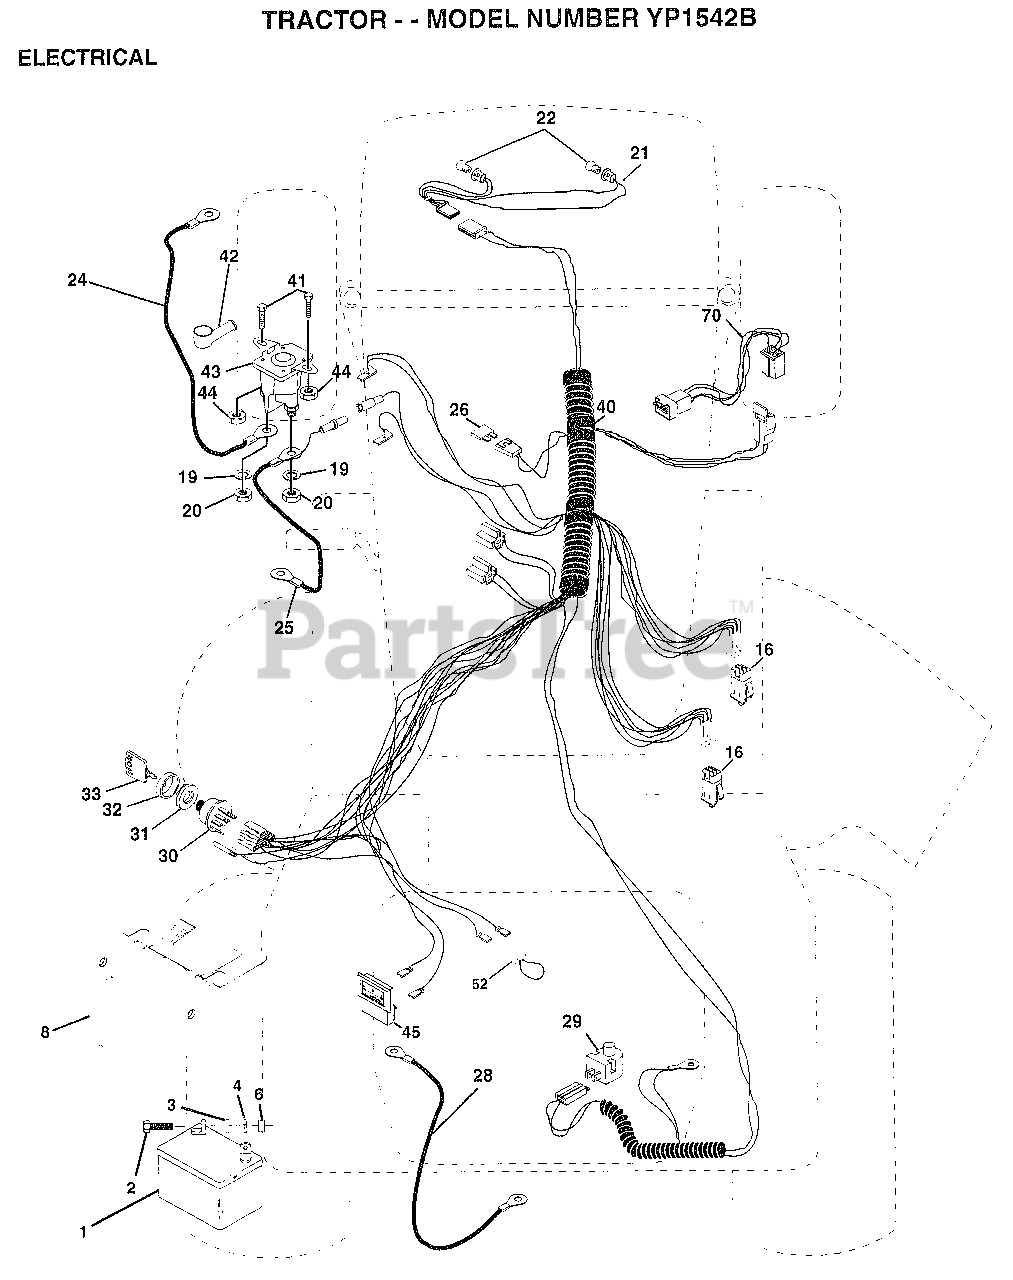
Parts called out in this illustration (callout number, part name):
3	WASHER
4	LOCKWASHER
8	"CASE,BATTERY.MECH"
16	SWITCH.INTERLOCK
20	NUT
21	"HARNESS,LIGHT SOC"
22	HEADLAMP BULB
24	"CABLE T, BATTERY"
25	CABLE.BTRY.6GA.RD
26	FUSE HYT
28	CABLE T
29	SWITCH.PLUNGER
30	SWITCH IGN 4POS
31	NUT IGNITION
32	COVER KEY SWITCH
33	KEY
40	HARNESS.IGNITION
41	BOLT HXHD FIN
44	NUT HXKEP 1/4X20
52	PROTECTION LOOP
70	HARNESS.ENG.B&S.
81	RELAY ASSY T
